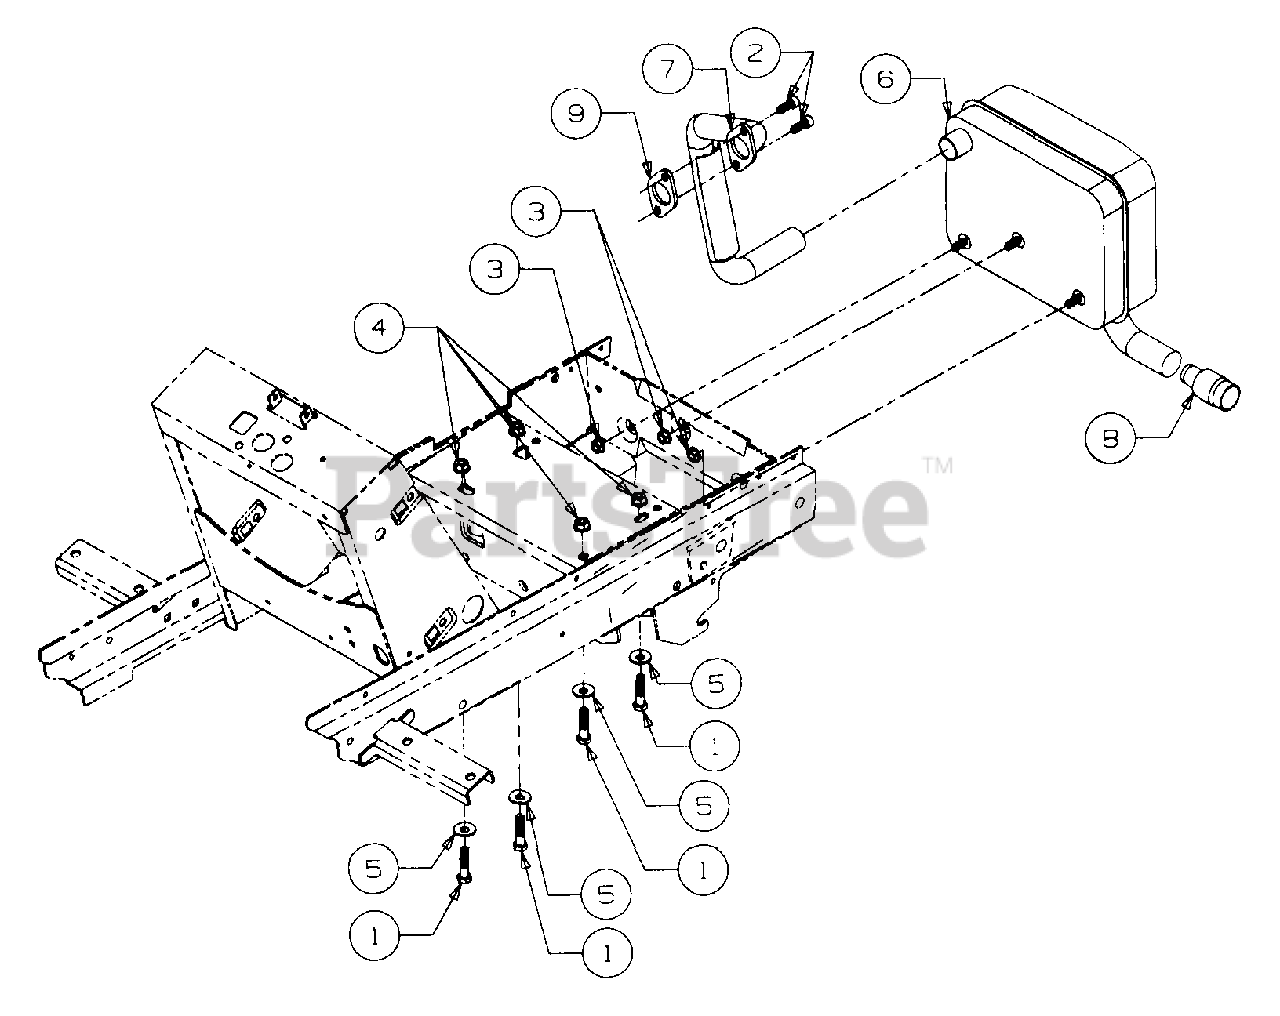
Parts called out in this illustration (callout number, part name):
1	Bolt, Engine Mtg, 3/8-24 x 1.75 Lg GR5
2	Screw, Socket Hd Cap, M8-1.25 x 20 mm Lg
3	Nut, Hex Flange Top Lock, 5/16-18
4	Nut, Hex Lock, 3/8-24
5	Washer, Bell, .380 x .88 x .062 Thk
6	Muffler Assembly
7	Tube, Exhaust
8	Arrestor, Spark
9	Gasket, Exhaust
